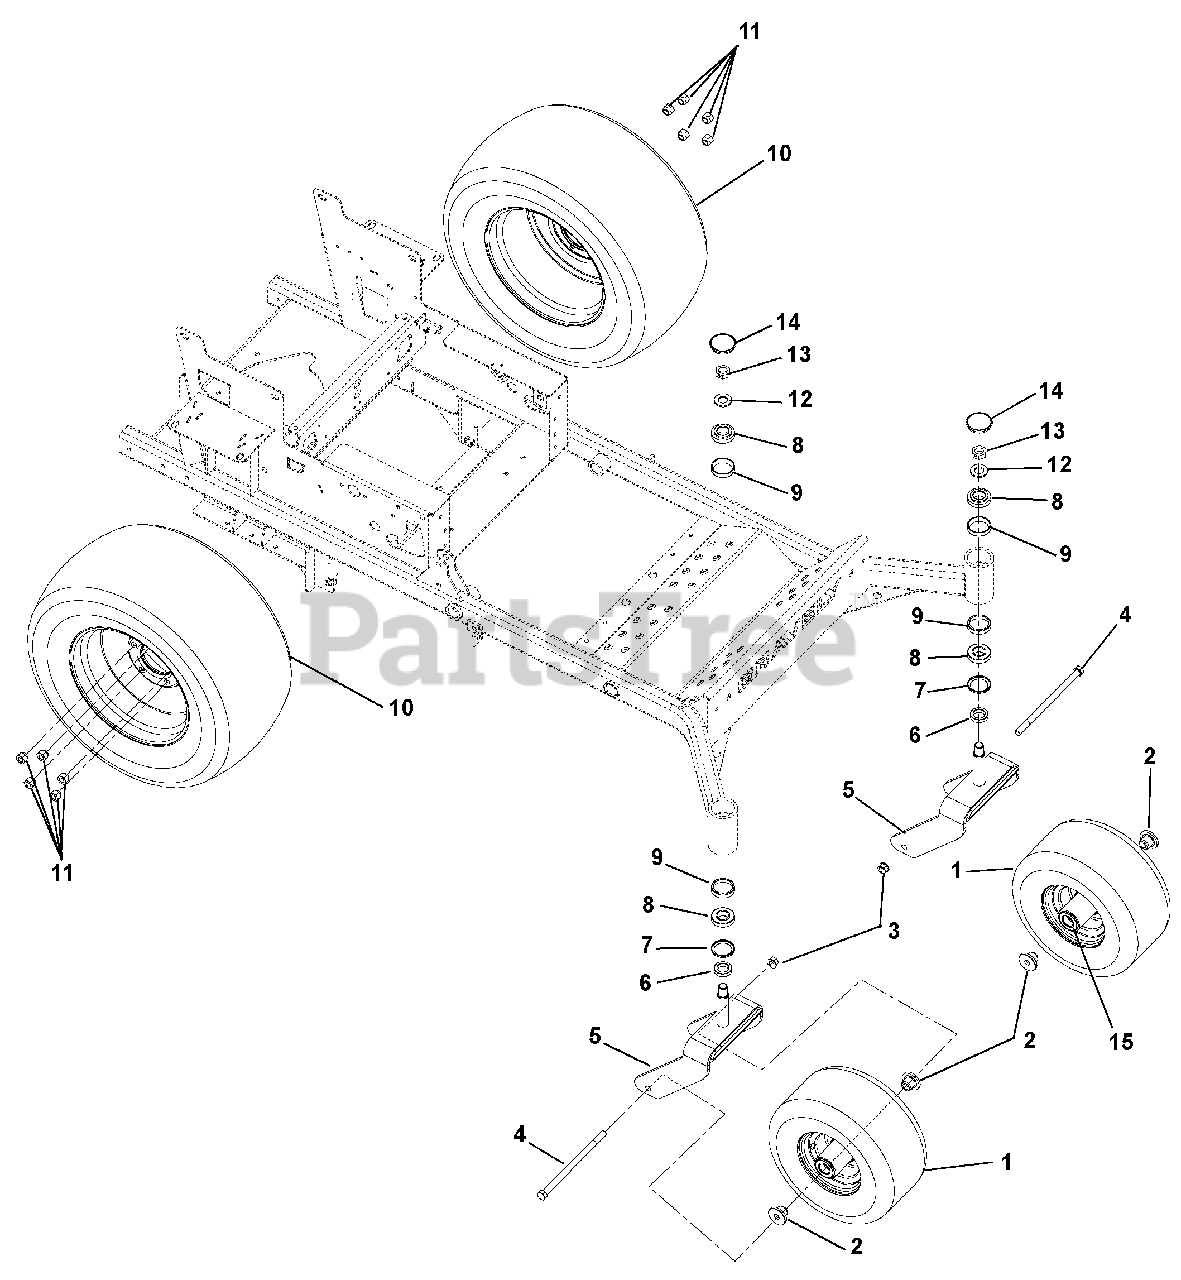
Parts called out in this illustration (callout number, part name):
1	Tire/Wheel Assembly, 13 x 6.50-6
2	Spacer, Front Wheel
3	Nut, .50-13 Nyloc Flange
4	Bolt, Hex .50-13 x 9.00
6	Spacer 1.258 x 1.75 x .550
7	Seal, Oil 1.75 x 2.332 x .312
8	Bearing, Cone 1.25 x .66
9	Bearing, Cup 2.328 x .465
10	Tire/Wheel Assembly, 23 x 10.50-12
11	Nut, Wheel .50-20 13/16 Across Flats, Automotive Type
12	Washer, Flat Steel .812 x 2.00 x .148
13	Nut, Jam Center-Lock .75-16
14	Cap, Dust
15	Bearing, 25 mm ID x 52 mm OD x 15 mm
